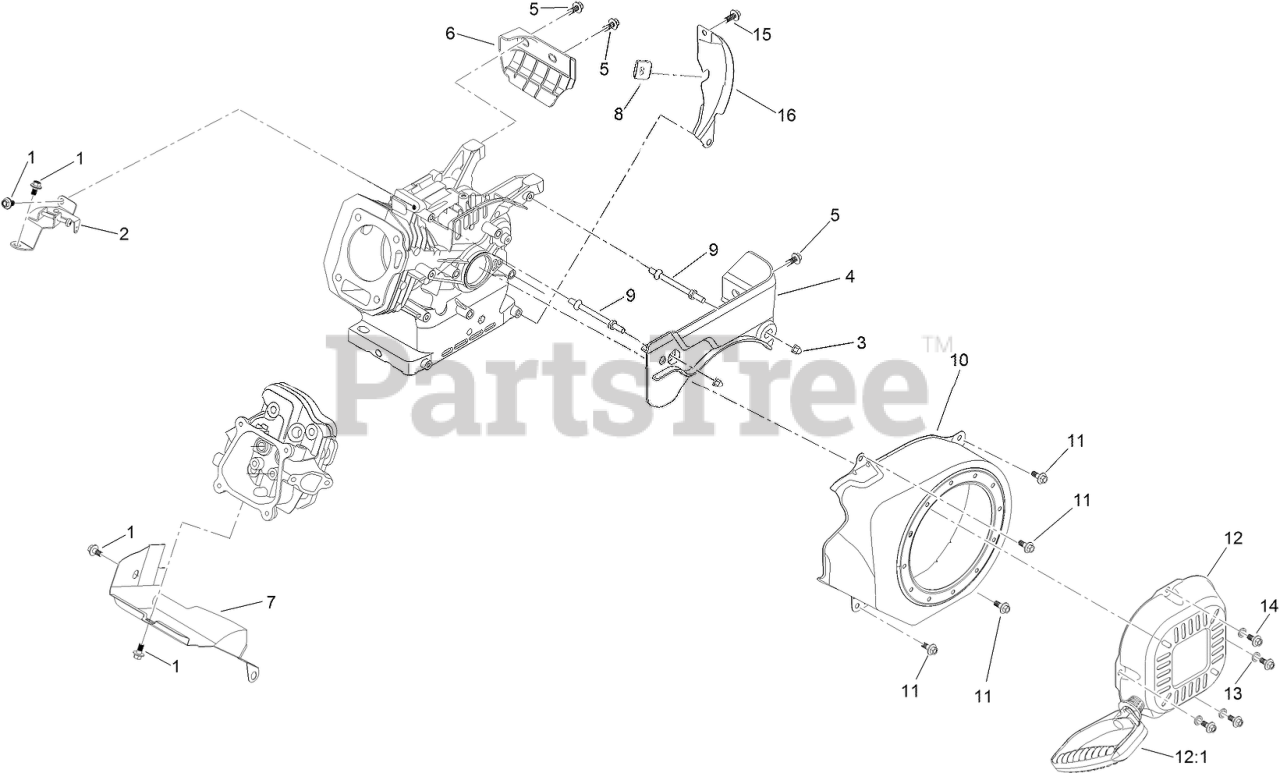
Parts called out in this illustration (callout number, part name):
1	SCREW-HHF
2	SPEED CONTROL ASM
3	NUT-ACORN
4	PANEL-FRONT
5	SCREW-HHF
6	PANEL-SIDE, ENGINE
7	SHROUD-LOWER
8	GROMMET-RUBBER
9	STUD-MOUNT
10	SHROUD-BLOWER
11	SCREW-HHF
12	RECOIL STARTER ASM
12:1	HANDLE-RECOIL
13	WASHER-PLAIN
14	SCREW-HHF
15	SCREW-HHF
16	SHIELD-FLYWHEEL
